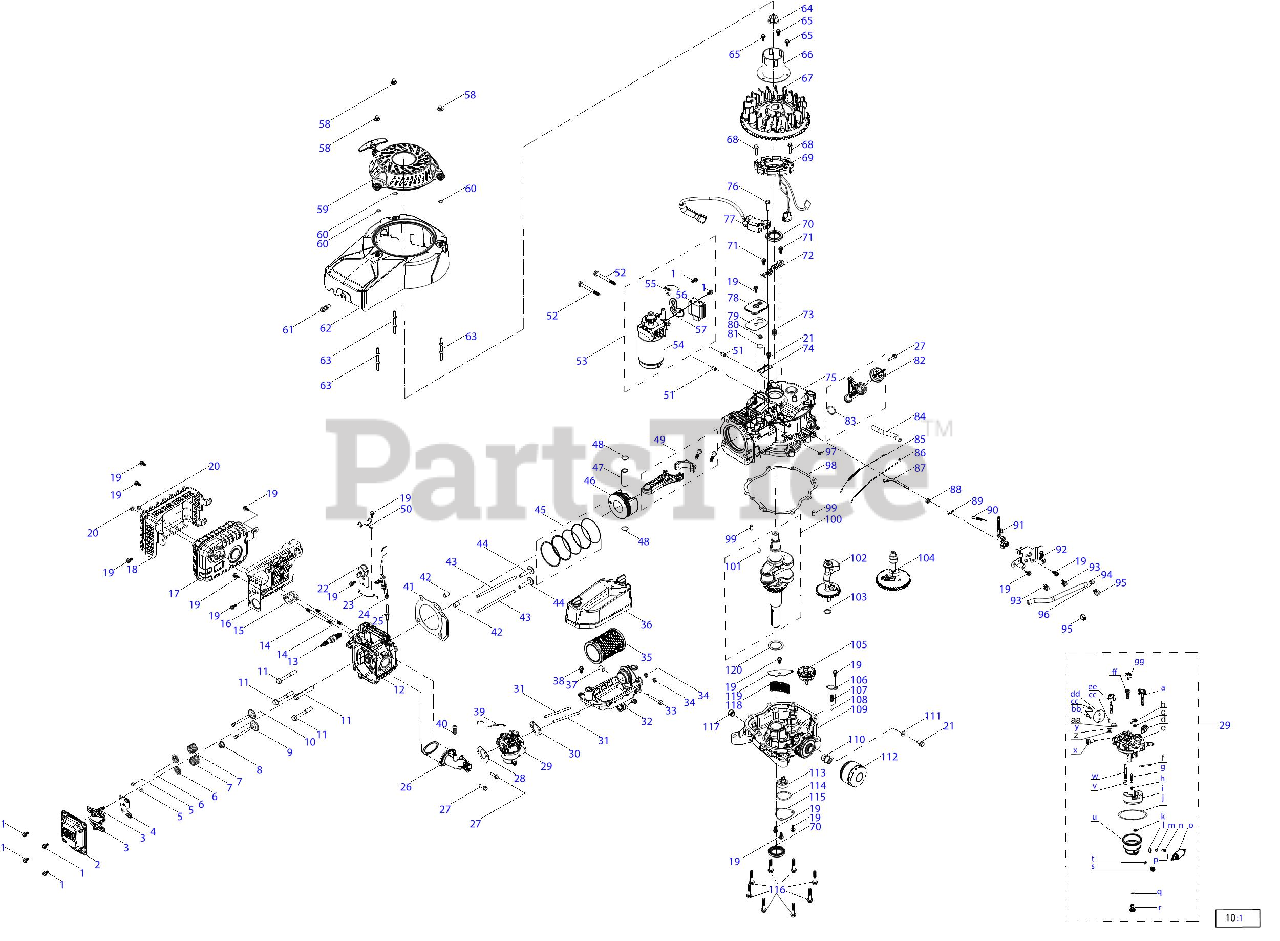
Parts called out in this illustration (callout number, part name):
1	Bolt, M6x16
2	Valve Cover
3	Rocker Arm Assembly
4	Rocker Arm Base
5	Valve Adjust Cap, Exhaust
6	Valve Spring Seat
7	Valve Spring
8	Intake Valve Seal
9	Exhaust Valve
10	Intake Vavle
11	Bolt, M10x1.25x70
12	Cylinder Head
13	Spark Plug
14	Stud, M8x102
15	Gasket, Muffler
18	Muffler Guard
19	Bolt, M6x14
21	Bolt, M6x12
22	Thermal Switch
23	Thermal Lever
24	Shield Assembly
26	Inlet Pipe
26	O-Ring,36x2.5
27	Bolt, M6x22
28	Gasket, Carburetor
29	Carburetor
30	Gasket, Air Filter
31	Stud, M6x92
32	Air Filter Base Assembly
33	Bolt, M6x55
35	Air Filter Element
36	Air Filter Cover Assembly
37	Bush, 11x6.6x30
38	Bolt, M6x18
39	Choke Lever
40	Self-tappling Screw, ST4.8x16
41	Gasket, Cylinder Head
42	Pin, 12x16
44	Tappet
45	Piston Ring Set
47	Piston Pin
48	Circlip
49	Connecting Rod Assembly
52	Bolt, M8x80
53	Electric Starter Assembly
54	Electric Starter
55	Flywheel Outlet Shield
58	Nut, M6
59	Recoil Starter
62	Blower Housing
63	Stud, M6x83
64	Nut, M20x1.5
65	Bolt, M6x10
66	Starter Cup
68	Bolt, M5x28
69	Charging Coil
70	Oil Seal, 35x52x7
71	Bolt, M5x10
72	Wire Board
73	Damping Pad
74	Wire Board
76	Bolt, M6x28
77	Ignition Module
78	Breather Cover
79	Gasket, Breather Cover
80	One-way Valve Spring
81	Breather Valve
82	Dipstick
83	O-Ring, Dipstick
84	Breather Hose
85	Idle Spring
86	Throttle Linkage
87	Governor Gear Shaft
88	Oil Seal, 6x11x4
89	Cotter Pin
90	Governor Spring
91	Governor Lever
92	Governor Gear Bracket Assembly
93	Clamp
94	Fuel Hose, 6.3x12.5x270
95	Clip
98	Gasket, Crankcase
99	Pin,9x14
100	Crankshaft
101	Woodruff Key
102	Balance Shaft
103	Washer, 17.2x1x26
105	Governor Gear
106	Breather Cover
108	Steel Ball, 8.731
109	Crankcase Cover
110	Connection Pipe
111	Washer,6.2x1.5x13
112	Oil Filter
114	Gasket, Oil Pump
115	Oil Pump Cover
116	Bolt, M8x40
117	Earth Bolt
118	Breather Filter Screen
119	Breather Cover
120	Washer, 35.4x1x52
